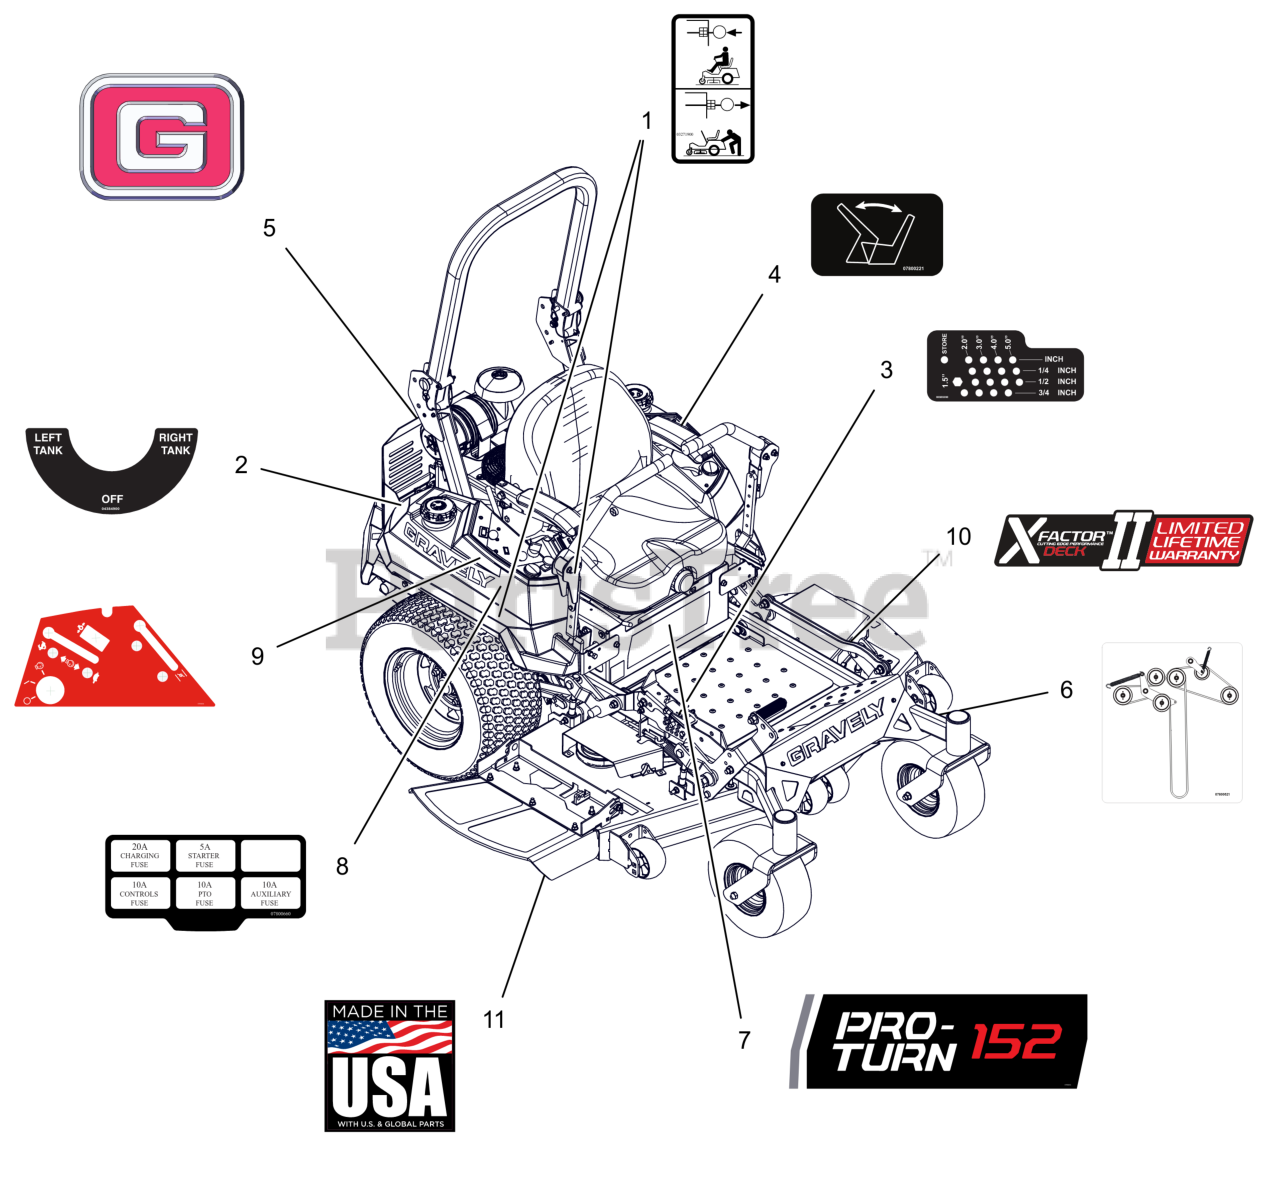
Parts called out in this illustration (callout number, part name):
1	DECAL, TRANSMISSION DISCONNECT
2	DECAL, FUEL VALVE
3	DECAL, HEIGHT OF CUT
4	DECAL - SEAT RELEASE
5	DECAL, GRAVELY BRAND
6	DCL,BELT ROUTE-RH V-SIDE IDLER
7	DECAL, PRO-TURN 152
8	DECAL, FUSE BLOCK
9	DECAL, NON-EFI CONTROL PANEL
10	DECAL, X-FACTOR DECK
11	DECAL, MADE IN USA
